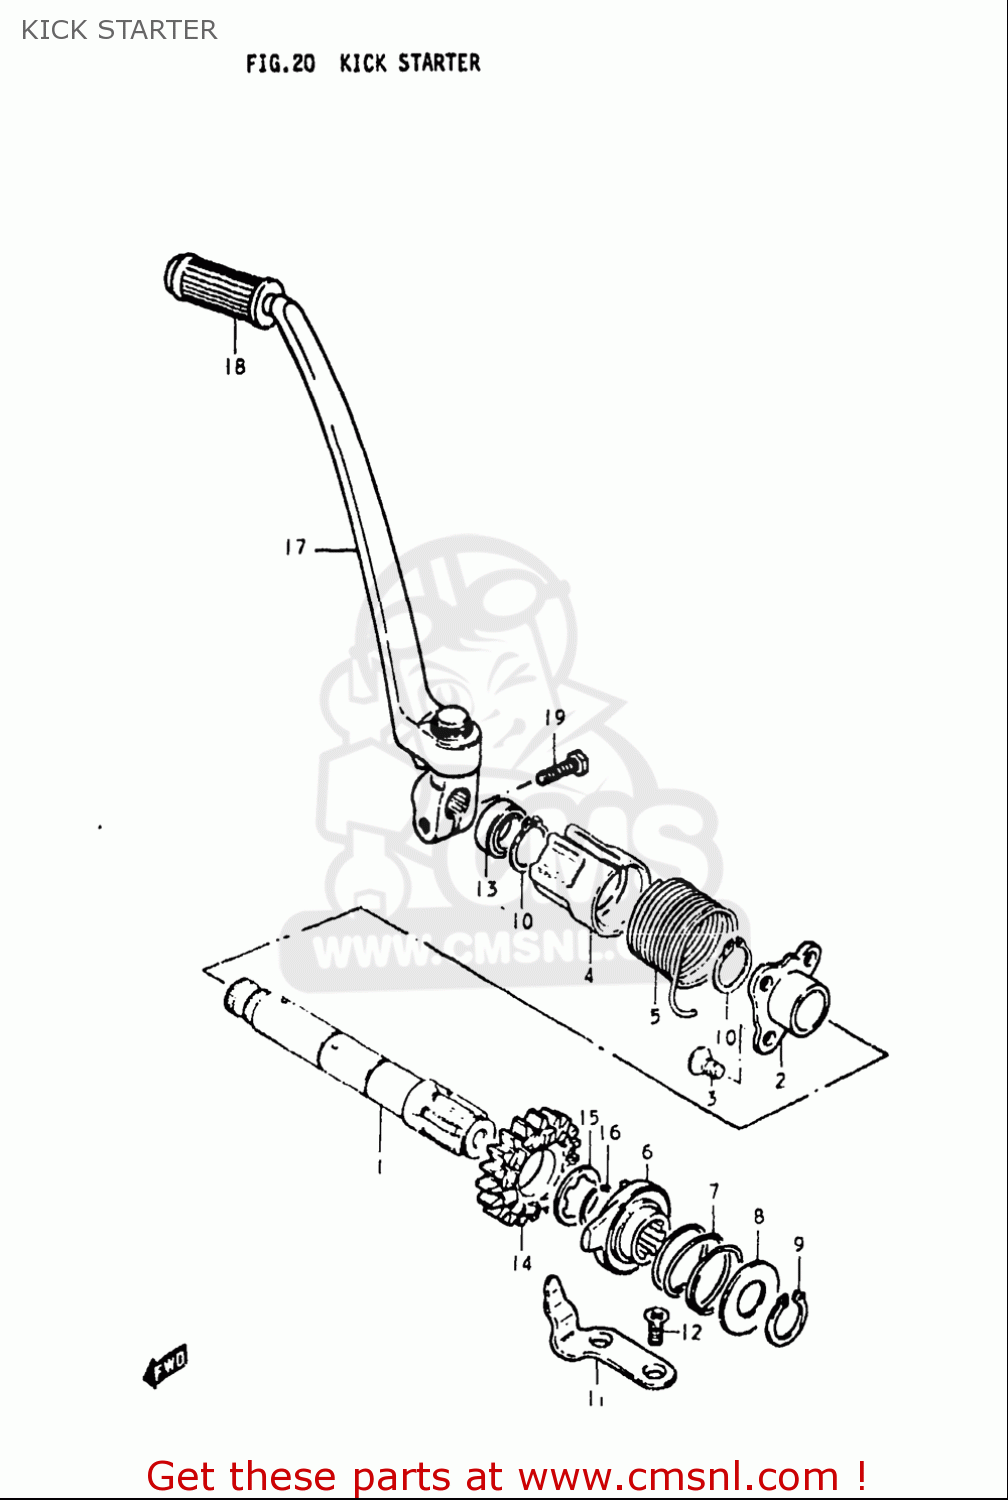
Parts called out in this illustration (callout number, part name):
3	SCREW
5	SPRING
6	STARTER,KICK
7	SPRING
9	CIRCLIP
10	CIRCLIP,20MM
12	SCREW
13	SEAL,OIL(20X27X5)
14	GEAR,KICK STARTER DRIVE
15	WASHER,LOCK
16	CIRCLIP
17	LEVER ASSEMBLY,KICK STARTER
18	RUBBER,KICK STARTER PEDAL
19	BOLT
